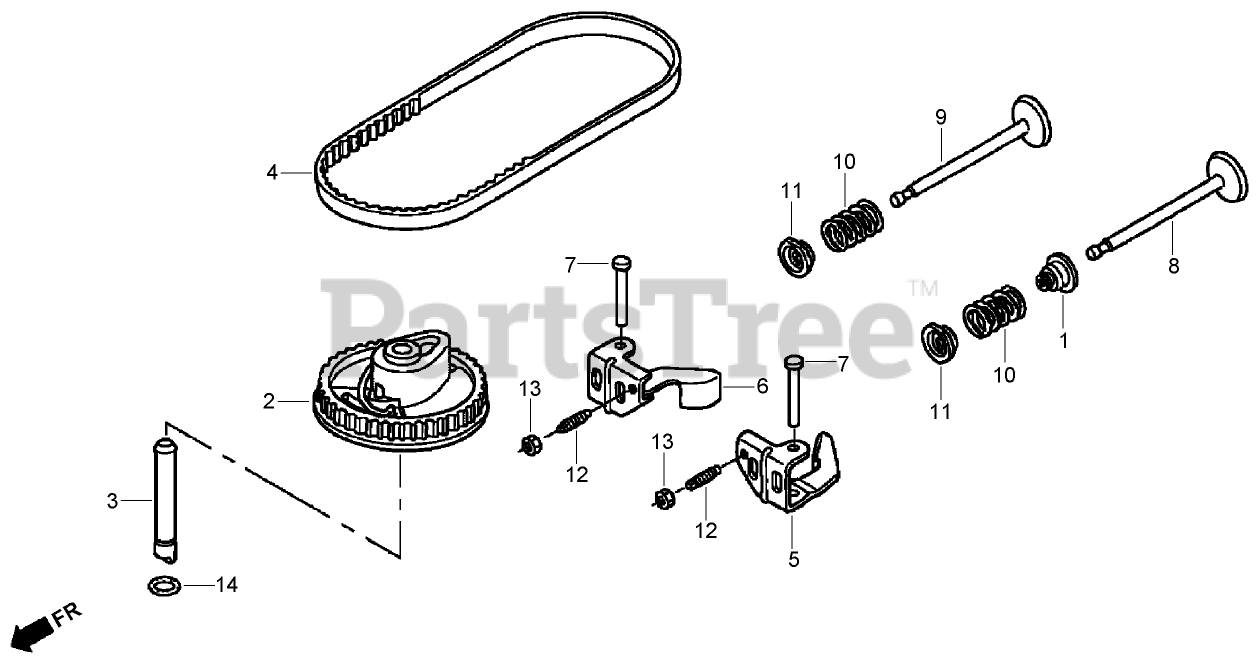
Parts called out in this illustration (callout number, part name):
1	SEAL-STEM, VALVE
2	PULLEY-CAMSHAFT
3	SHAFT-PULLEY, CAM
4	BELT-TIMING (84H U7 G-200)
5	ARM-ROCKER, INTAKE VALVE
6	ARM-ROCKER, EXHAUST VALVE
7	SHAFT-ARM, ROCKER
8	VALVE-INTAKE (TECHNOSTAR)
8	VALVE-INTAKE (ROCKNEL)
9	VALVE-EXHAUST
10	SPRING-VALVE
11	RETAINER-SPRING, VALVE
12	SCREW-ADJUSTING, TAPPET
13	NUT-ADJUSTING, TAPPET
14	O-RING (6.8X19) (ARAI)
